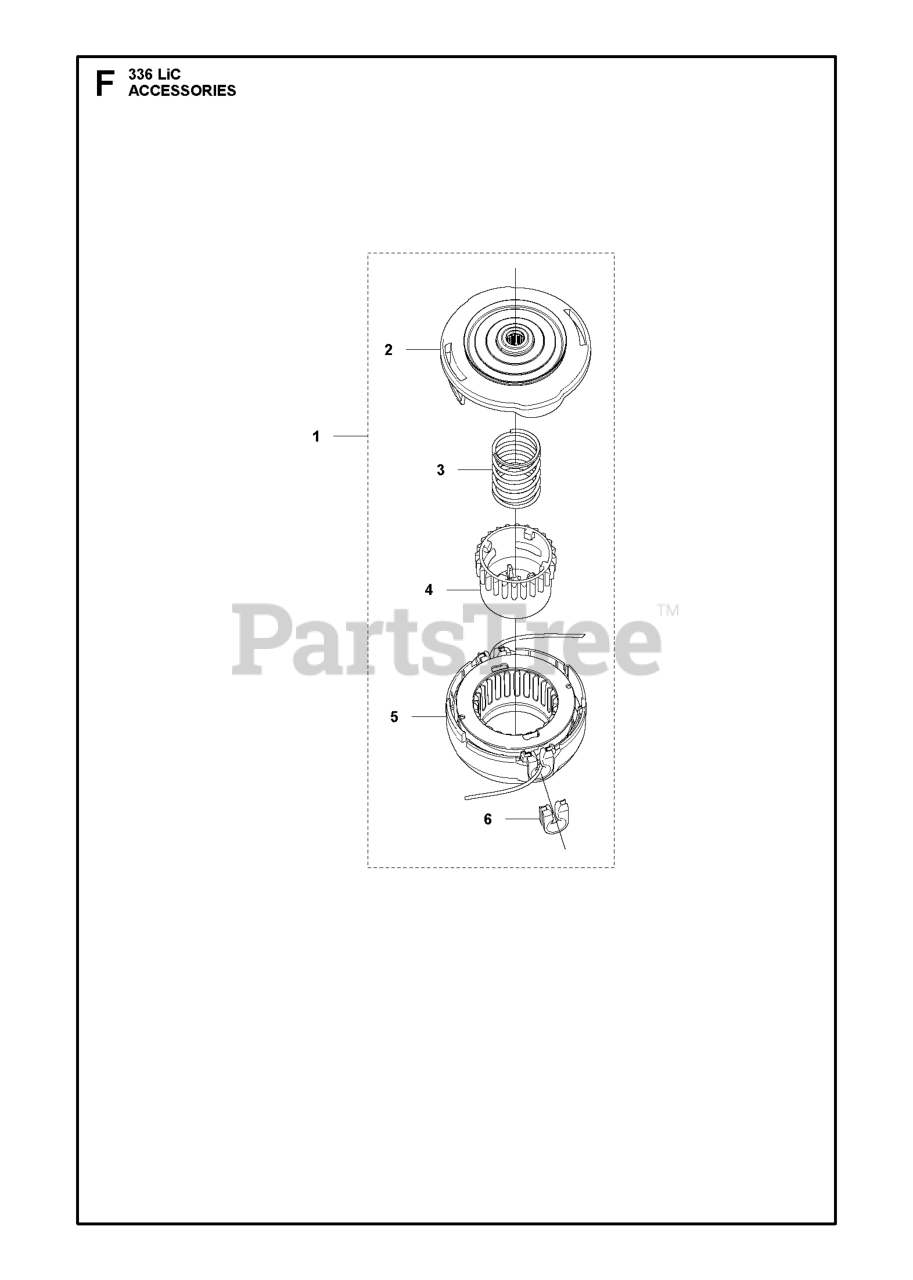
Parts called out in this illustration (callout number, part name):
1	TRIMMER HEAD T25B M10
1	CRANKCASE CPL
2	HOUSING ASSY TRIMMERHEAD T25B
3	FELLING DOG
4	FELLING DOG
5	SCREW MC6S 5X35
6	SCREW MC6S 5X20
8	CHOKE CONTROL
9	SCREW MC6S 4X16
10	WASHER 4.2X9
14	OIL TANK VENT
15	PIN 5X14
16	CHAIN TENSIONER
17	CHAIN CATCHER
18	SCREW MC6S 5X12
20	CHAIN GUIDE
21	SCREW MC6S 5X50
22	PROTECTION PLATE
26	SWITCH ON/OFF
27	CRANKCASE CPL
28	SCREW MC6S 5X12
29	SEALING RING
32	OILCAP GASKET
33	GASKET SET
